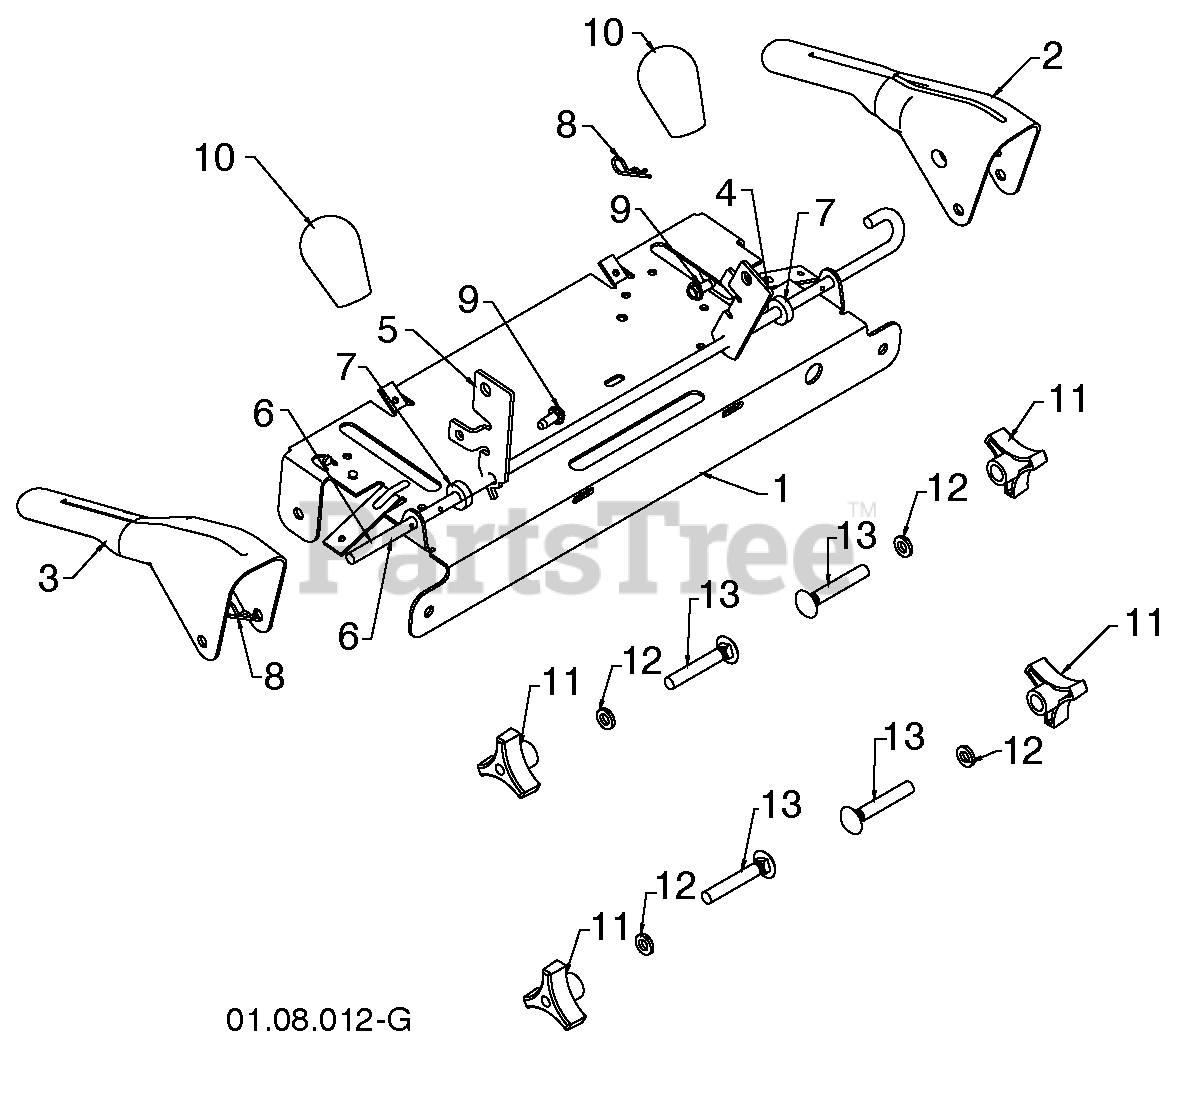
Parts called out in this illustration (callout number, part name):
1	PANEL.CONTROL.PNT.BLA
2	LEVER.CONTROL.LH.BLACK
3	LEVER.CONTROL.RH.GREY
4	ARM.TRACTION.ROD.YZ
5	ARM.IMPELLER.ROD.SNOW
6	BAIL.CONTROL.INTERLOCK
7	SPACER.CONTROL.LEVER
8	SPRING RETAINER
9	SCREW 14-20 X 5/8
10	KNOB.OVERMOLD.DS.HUSQVARNA/BLK
11	KNOB.HANDLE.3/8.TRI-POINT.BLAC
12	WASHER
13	BOLT 3/8-16 X 2-1/4
